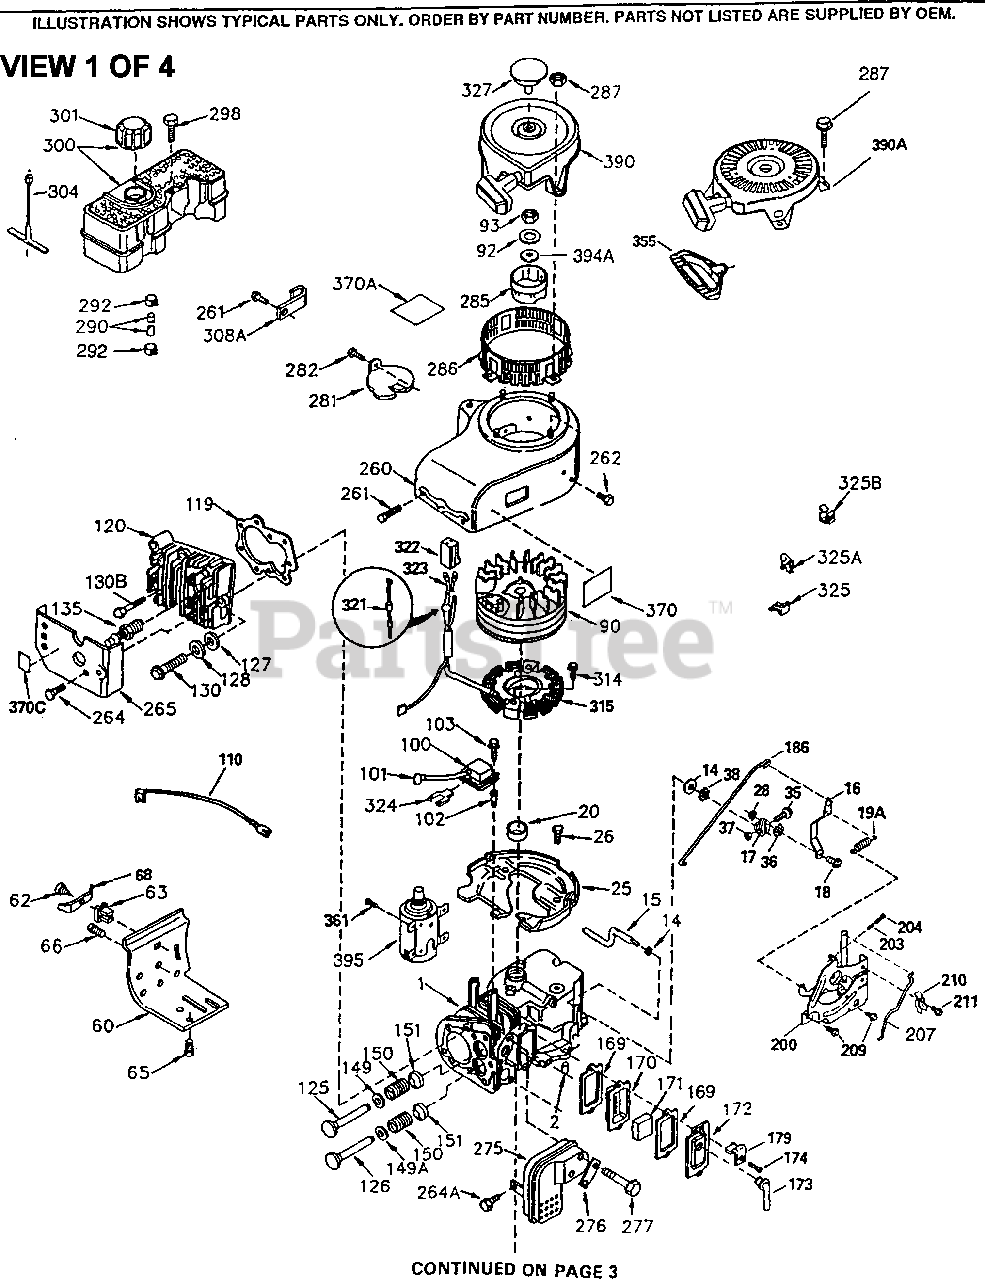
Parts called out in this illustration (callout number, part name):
1	"Cylinder (Incl. 2 & 20)
2	Dowel Pin
14	Flat Washer
15	Governor Rod
16	Governor Lever
17	Governor Lever Clamp
18	Screw, 8-32 x 5/16"
19A	Extension Spring
20	Oil Seal
25	Blower Housing Baffle
26	Screw, 1/4-20 x 5/8"
28	Lock Nut, 8-32
35	Screw, 10-32 x 3/4"
36	Lock Washer #8
37	Lock Nut, 10-32
38	Retaining Ring
60	Blower Housing Extension
62	Screw, 8-32 x 3/8"
63	Breather Tube Grommet
64	Screw, 5/16-18 x 15/32"
65	Screw, 10-24 x 1/2"
68	Ground Terminal
90	Flywheel
92	Lock Washer
93	Flywheel Nut
100	Solid State Ignition
101	Spark Plug Cover
102	Solid State Mounting Stud
103	Screw, Torx T-15, 10-24 x 15/16"
110	Ground Wire
119	* Cylinder Head Gasket
120	Cylinder Head
125	Exhaust Valve (Std.)(Incl. 151)
125	Exhaust Valve (1/32" OS) (Incl. 151)
126	Intake Valve (Std.) (Incl. 151)
126	Intake Valve (1/32" OS) (Incl. 151)
128	Belleville Washer
130	Screw, 5/16-18 x 2"
135	Resistor Spark Plug - RJ17LM
149	Valve Spring Cap
149A	Valve Spring Cap
150	Valve Spring
151	Valve Spring Keeper
169	* Valve Cover Gasket
170	Breather Body
171	Breather Element
172	Valve Cover
173	Breather Tube
174	Screw, 10-24 x 1/2"
186	Governor Link
200	Control Bracket (Incl. 203 & 204)
203	Compression Spring
204	Screw, 6-32 x 21/32"
207	Throttle Link
209	Screw, 10-32 x 7/16"
210	Conduit Clip
211	Screw, 10-32 x 3/8"
260	Blower Housing
261	Screw, 5/16-18 x 3/4"
262	Screw, T-40, 5/16-24 x 21/32"
264A	Screw, 1/4-20 x 5/8"
265	Cylinder Head Cover (Black)
275	Muffler
276	Locking Plate
277	Screw, 5/16-18 x 3-3/16"
286	Cup & Screen
290	Fuel Line
292	Fuel Line Clamp
298	Screw, 10-32 x 35/64"
300	Fuel Tank (Incl. 292, 298 & 301)
301	Fuel Cap
314	Screw, 1/4-20 x 3/4"
315	Alternator Coil (3 Amp) Incl. 321 - 3 23
322	Connector Body
323	Terminal
325	Wire Clip
325A	Wire Clip
361	Screw, Torx T-30, 1/4-20 x 15/32"
370	Lubrication Decal
395	Electric Starter Motor (12 Volt)
